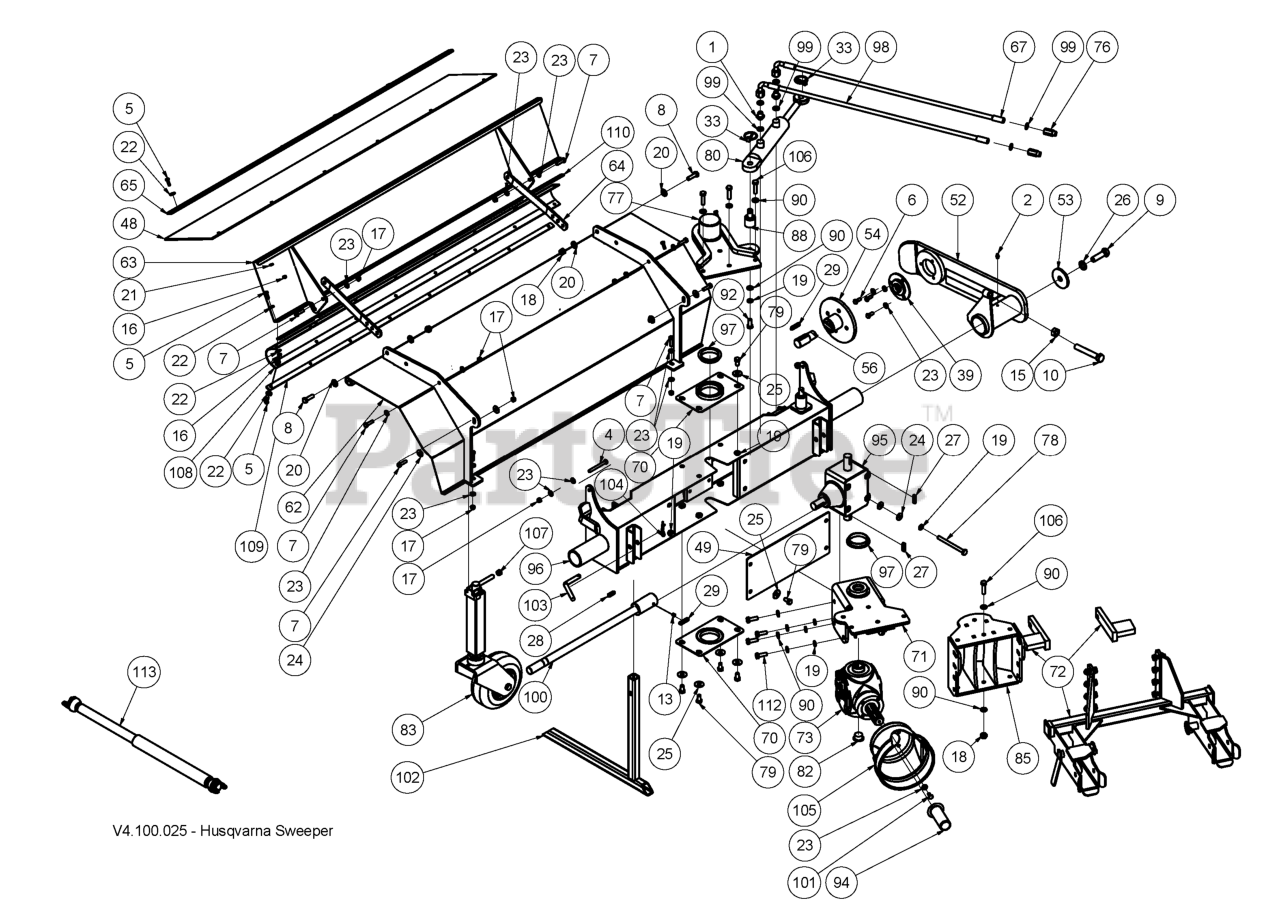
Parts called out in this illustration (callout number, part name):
16	LOCKNUT M6
17	LOCKNUT M8
18	NUT
22	WASHER - 26X6.5X1.6
23	WASHER BRB 8.4X17
88	WASHER
101	BOLT - M8X16
